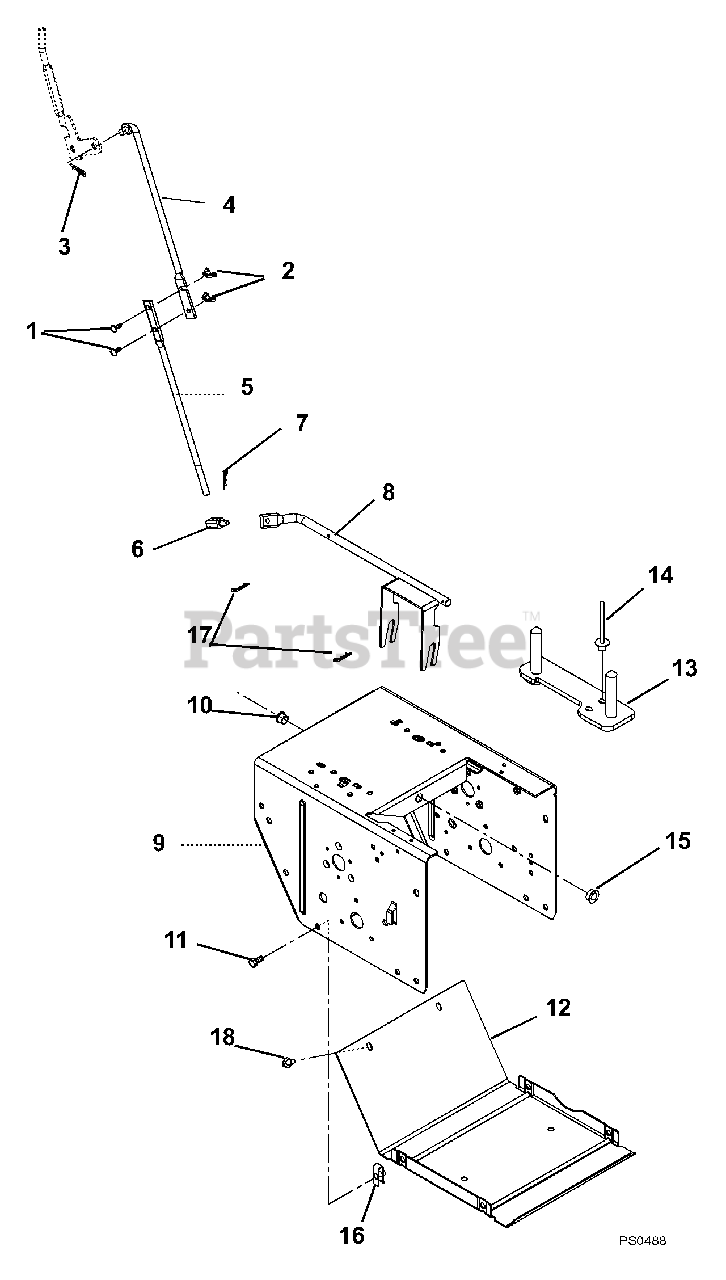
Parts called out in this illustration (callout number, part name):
1	@BLT-RDHDSQNK .25-20X1.00 G5YZ
2	NUT-LK WING .250-20 YWZC
3	PIN-HAIR, ENDRIES #25 YWZC
4	ROD, SHIFT-UPPER
5	ROD, SHIFT-LOWER
6	PIVOT,SHIFT ROD .375-16(TRUNN)
7	PIN-HAIR, ENDRIES #25 YWZC
8	ARM, SHIFT-WELDMENT
9	FRAME, MAIN
10	BUSHING, POLYLINER-.50 SPLIT
11	@SCR-MCH .25-20X.75 HWH YWZC
12	COVER, BOTTOM
13	STRAP, ENGINE BOLT-WELDMENT
14	RVT-POP .187X.45 DOME SS FBF64
15	BUSHING, POLYLINER-.50 SNAPIN
16	NUT-RTNR .25-20X.56
17	CLIP, SPRING
18	@SCR-TAP .25-20X.50 HWH TR YWZ
